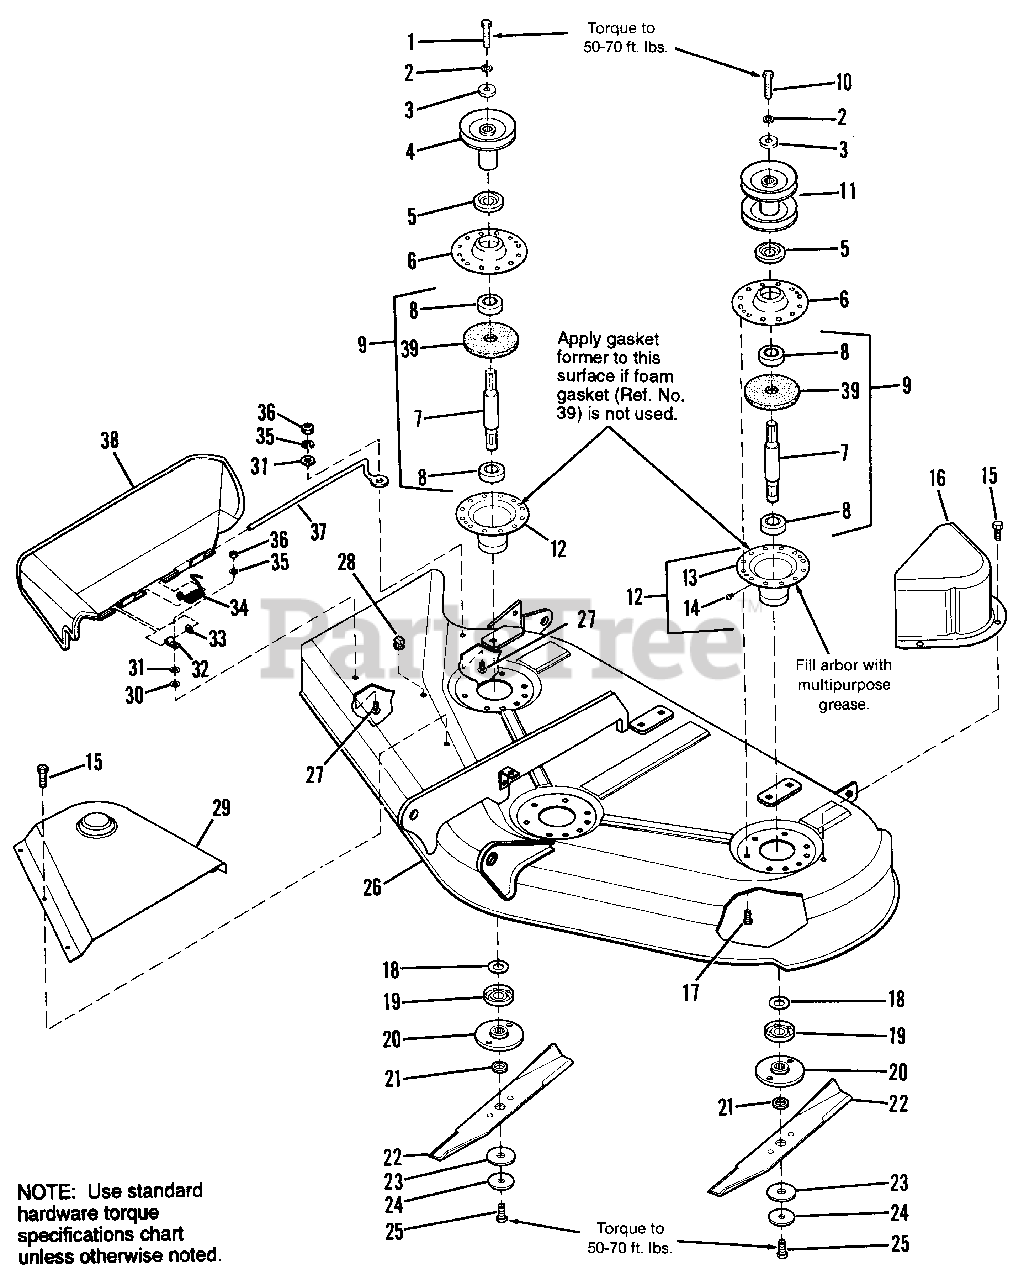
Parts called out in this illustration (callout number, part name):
1	CAPSCREW, Hex Hd., 7/16-14 x 1-1/4
2	LOCKWASHER, 7/16
3	WASHER, Plain
4	PULLEY ASSY., Deck Drive
5	SHIELD, Bearing Upper, Arbor
6	HOUSING, Arbor, Top
7	SHAFT, Arbor (Incl. Ref. No. 21)
9	SHAFT 8 BEARING ASSY. (Center & Outer) (Incl. Ref. Nos. 7, 8, 8 39 )
10	CAPSCREW, Hex Hd., 7/16-14 x 3-1/2
11	PULLEY ASSY.
12	HOUSING ASSY., Arbor, Bottom (Incl. Ref. Nos. 13 & 14)
14	GREASE FITTING
15	SCREW, Hex, Taptite, 5/16 x 1/2
16	COVER, Arbor
17	SCREW, Hex, Taptite, 5/16 x 3/4
18	WASHER, Shim
19	SHIELD, Grass, Bottom
20	ADAPTOR, Blade
21	COLLAR, Mower Arbor
22	BLADE, Mower, 16-1/8
22	BLADE, Mower, 50"
23	WASHER, Spline
24	WASHER, Spring
25	CAPSCREW, Hex Hd., 7/16-14 x 1
26	HOUSING ASSY., 44" (Orange)
26	HOUSING ASSY., 44" (Black)
26	HOUSING ASSY., 50" (Orange)
26	HOUSING ASSY., 50" (Black)
27	CARRIAGE BOLT, 1/4-20 x 7/8
29	COVER, Arbor
30	NUT, Push On
31	WASHER, Flat
33	WASHER, Plain, 5/16
35	LOCKWASHER, 1/4
36	NUT, Hex, 1/4-20
37	ROD, Deflector, Front
38	DEFLECTOR, Plastic
39	GASKET, Foam
